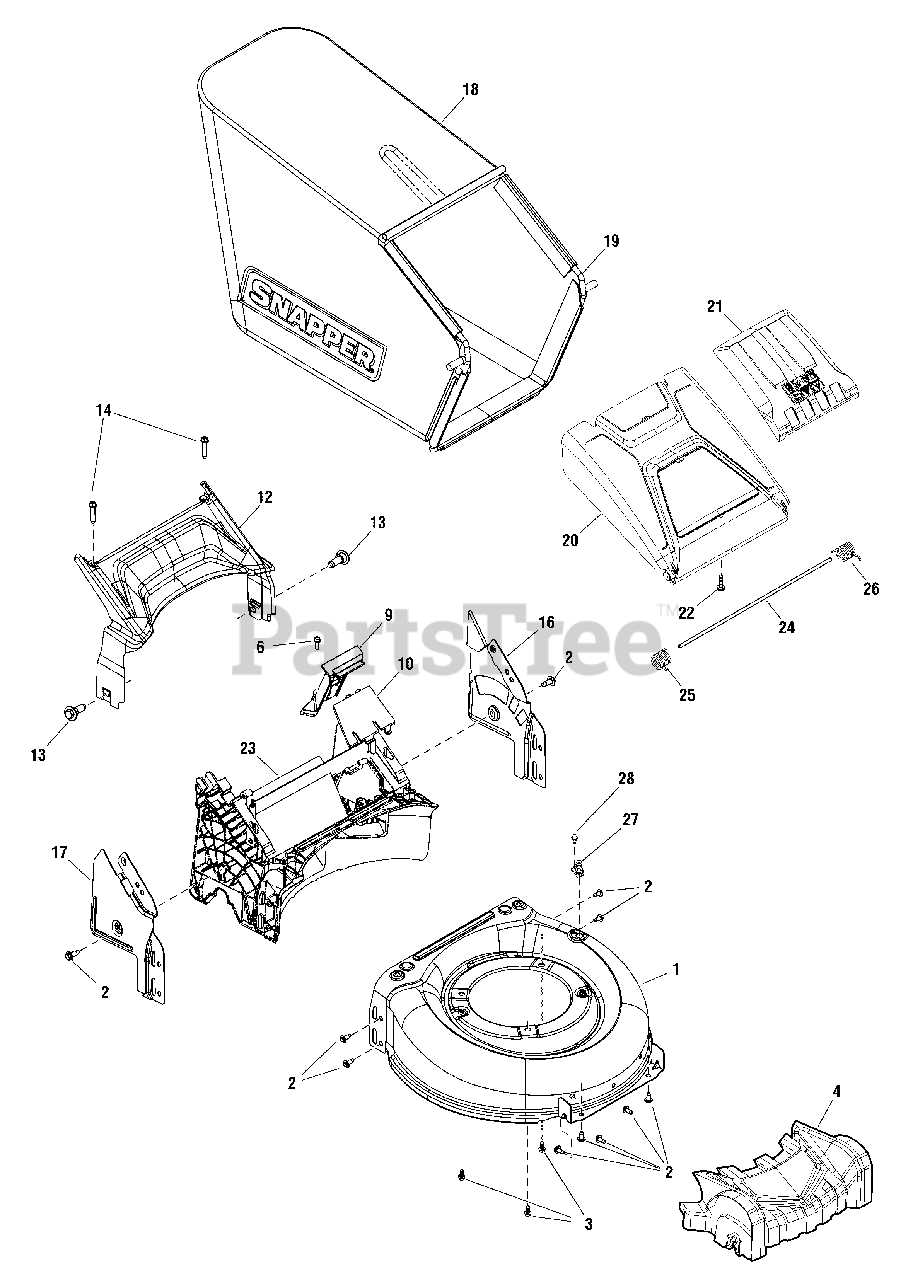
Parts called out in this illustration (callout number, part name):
2	SCREW, Hex Head
3	SCREW, 3/8-16 x 1
4	FRONT COVER, Deck
6	SCREW, 1/4-15X3/4, Self-Tapping, BZ
9	COVER, Rear
10	COVER, Front
12	COVER, Rear
13	SCREW, 5/16-14
14	SCREW, 1/4-15 x 1-1/4
16	SUPPORT, Handle, LH
17	SUPPORT, Handle, RH
20	REAR FLAP
21	COVER, Gray
22	SCREW #10-16 x 3/4
23	GUIDE, Rear
25	TORSION SPRING, RH
26	TORSION SPRING, LH
27	NOZZLE, Wash
28	SCREW, 1/4-20 x 1/2
